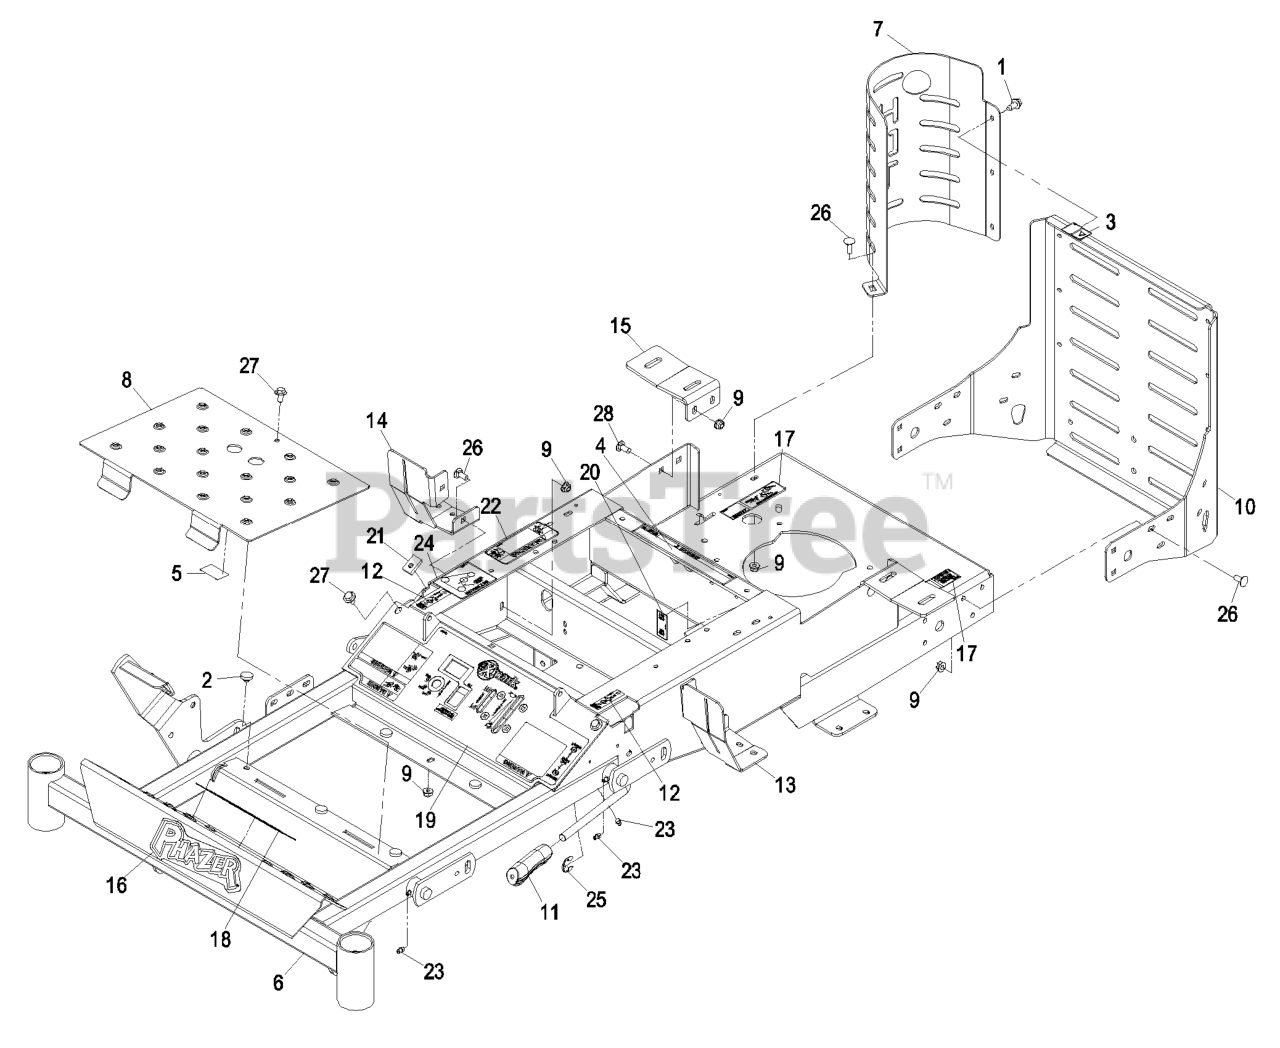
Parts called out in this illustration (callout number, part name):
1	Screw-HWH 5/16-18 X 3/4 Tf
3	DECAL-SURFACE, HOT
4	DECAL-BATTERY
5	DECAL-GUARD
6	ASM,PHAZER FRAME W/DECALS
7	GUARD-MUFFLER
9	NUT-HF, NI
10	REAR GUARD ASM
11	GRIP-LEVER, BRAKE
12	DECAL-CONTROL, MOTION
13	MOUNT-TANK, FUEL (LH)
14	MOUNT-TANK, FUEL (RH)
15	BRACKET-FUEL TANK, REAR
16	DECAL,PHAZER
17	DECAL,ZT DUMP
18	DECAL-SLOPE, DANGER
19	DECAL,CONSOLE
20	DECAL-RELAY
21	STOP-MOTION
22	DECAL-DEVICES, ROTATING
23	FITTING-GREASE
24	DECAL,BELT ROUTING
26	SCREW-CARR
27	SCREW-HHF
28	SCREW-CARR
